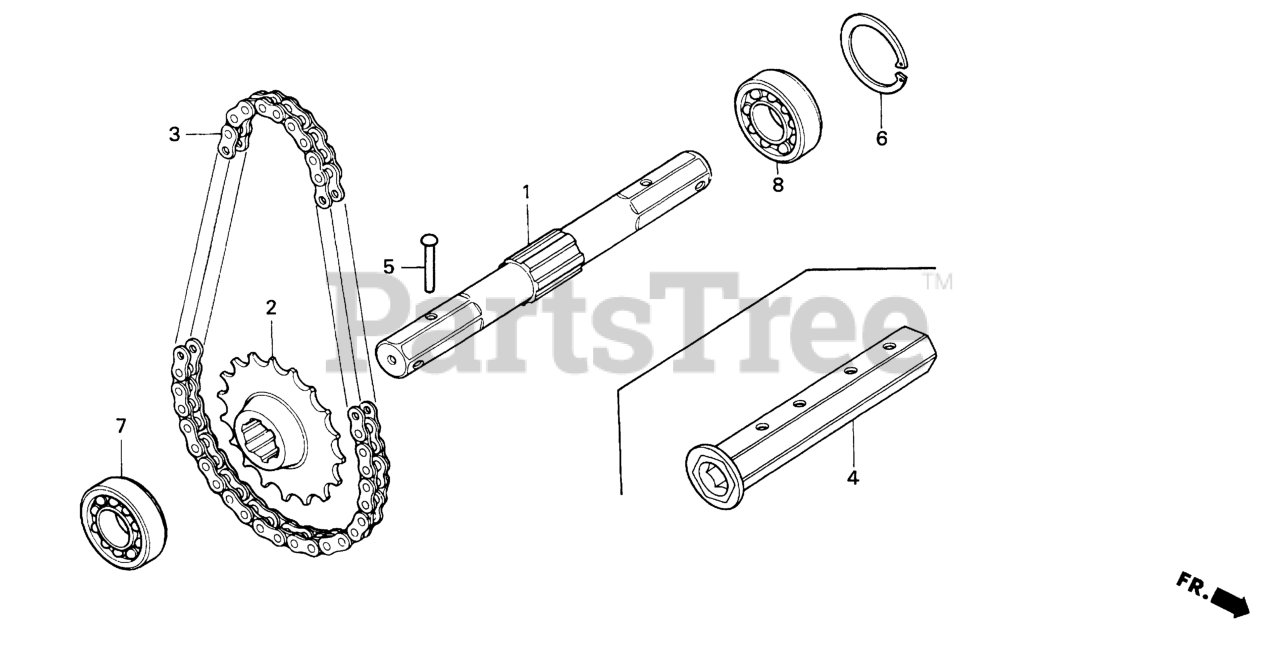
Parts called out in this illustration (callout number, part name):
1	SHAFT, WHEEL
2	SPROCKET, DRIVEN
3	CHAIN, FINAL (RK520KFX44LE)
4	SHAFT A, EXTENSION (23X32X179)
5	PIN (7X48)
6	CIRCLIP (INNER) (52MM)
7	BEARING, RADIAL BALL (6005)
8	BEARING, RADIAL BALL (6205)
